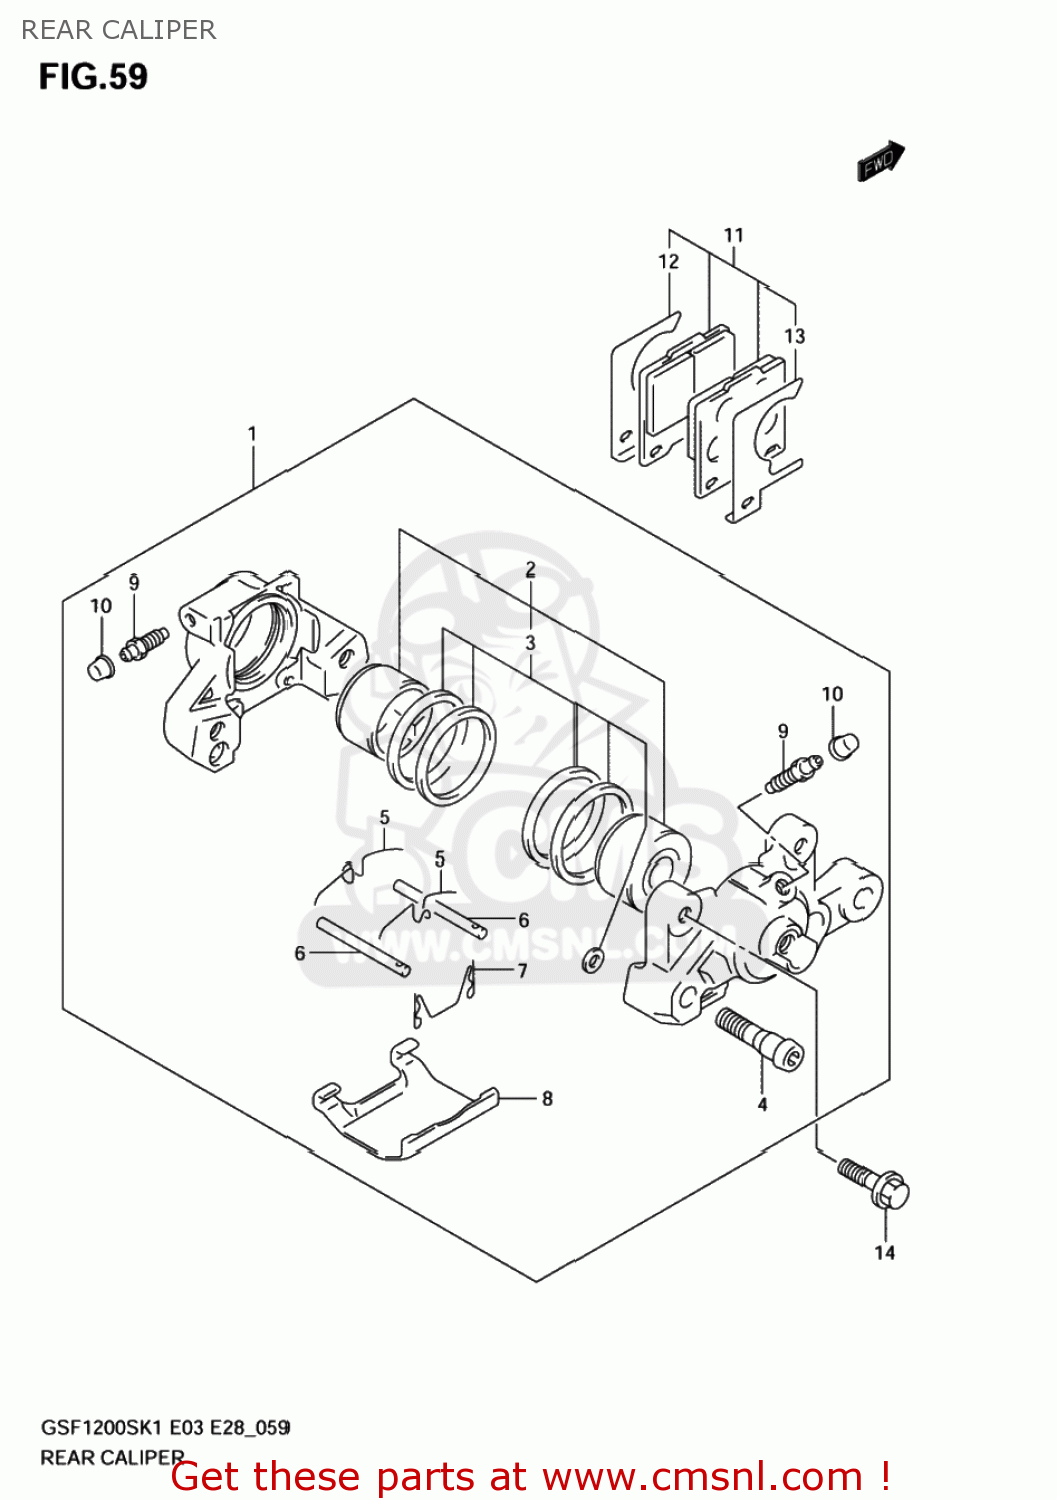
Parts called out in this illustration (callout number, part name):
1	CALIPER ASSY,RR
2	PISTON SET
3	SEAL SET,PISTON
4	BOLT,HOUSING
5	SPRING
6	PIN,PAD
7	CLIP,PAD PIN
8	COVER
9	BLEEDER
10	CAP,BLEEDER PLUG
11	PAD & SHIM SET (NAS)
12	SHIM,INNER
13	SHIM,OUTER
14	BOLT
